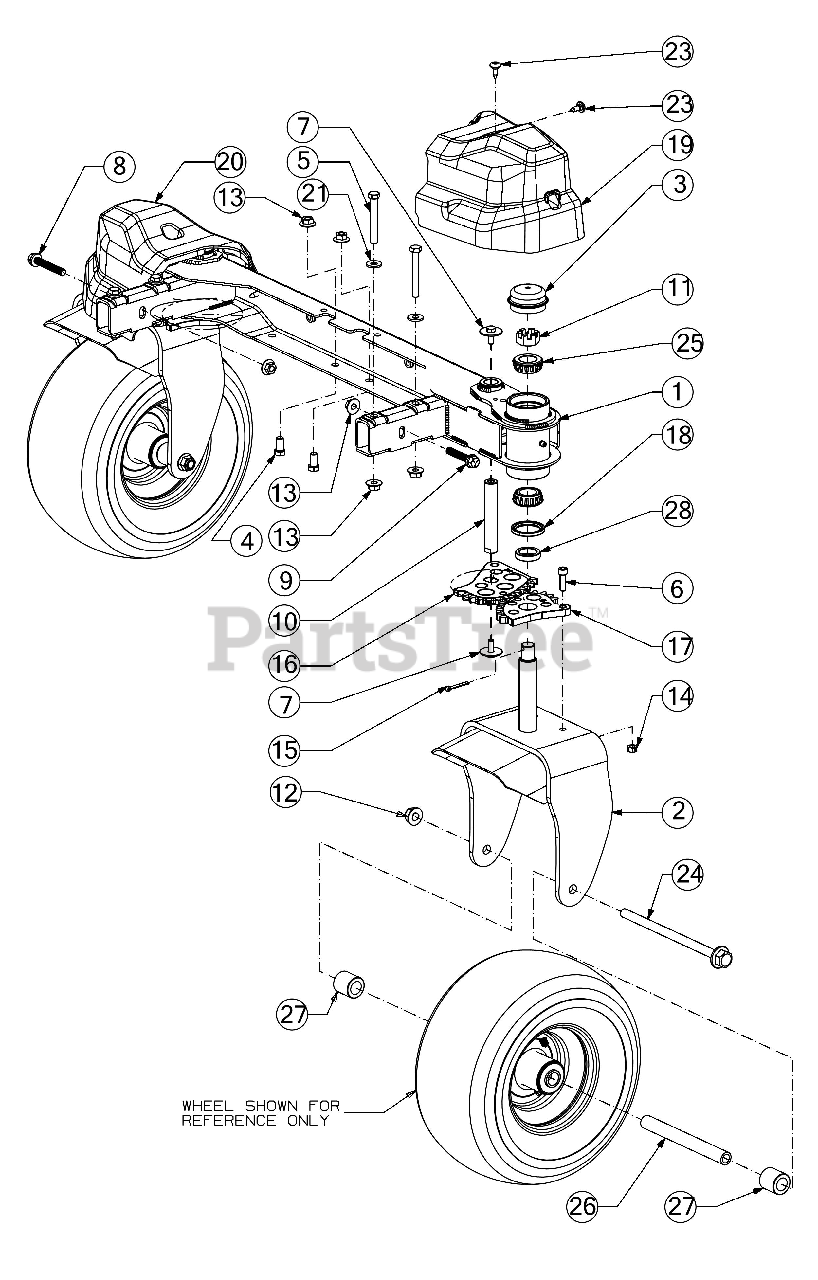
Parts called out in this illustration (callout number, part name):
1	AXLE-FRONT SYNC
3	AXLE GREASE CAP
4	HEX SCREW 3/8-16 X .75
5	SCREW 3/8-16 X 2.75 GR5
6	SCREW 5/16-18X1.25
7	SCREW 5/16-18 X.75 GR5
8	SCREW 3/8-16 X 2.25 GR5
9	SCREW 3/8-16 X 2.00 GR5
10	STEERING GEAR PIVOT SHAFT
11	HEX NUT CASTLE 3/4-16
13	FLANGE LOCK NUT
14	HEX NUT
15	COTTER PIN-5/32 DIA
16	STEERING GEAR
17	STEERING SPUR GEAR 13T
19	AXLE COVER (RH)
20	AXLE COVER (LH)
21	FLAT WASHER .385X.870X.090
23	TORX SHOULDER SCREW 1/4-20
24	SCREW 1/2-13X8.5 GR5
25	ROLLER BEARING 47MM X 25MM X 15MM
26	CASTER AXLE SPACER
27	SPACER .76X1.23X1.25
